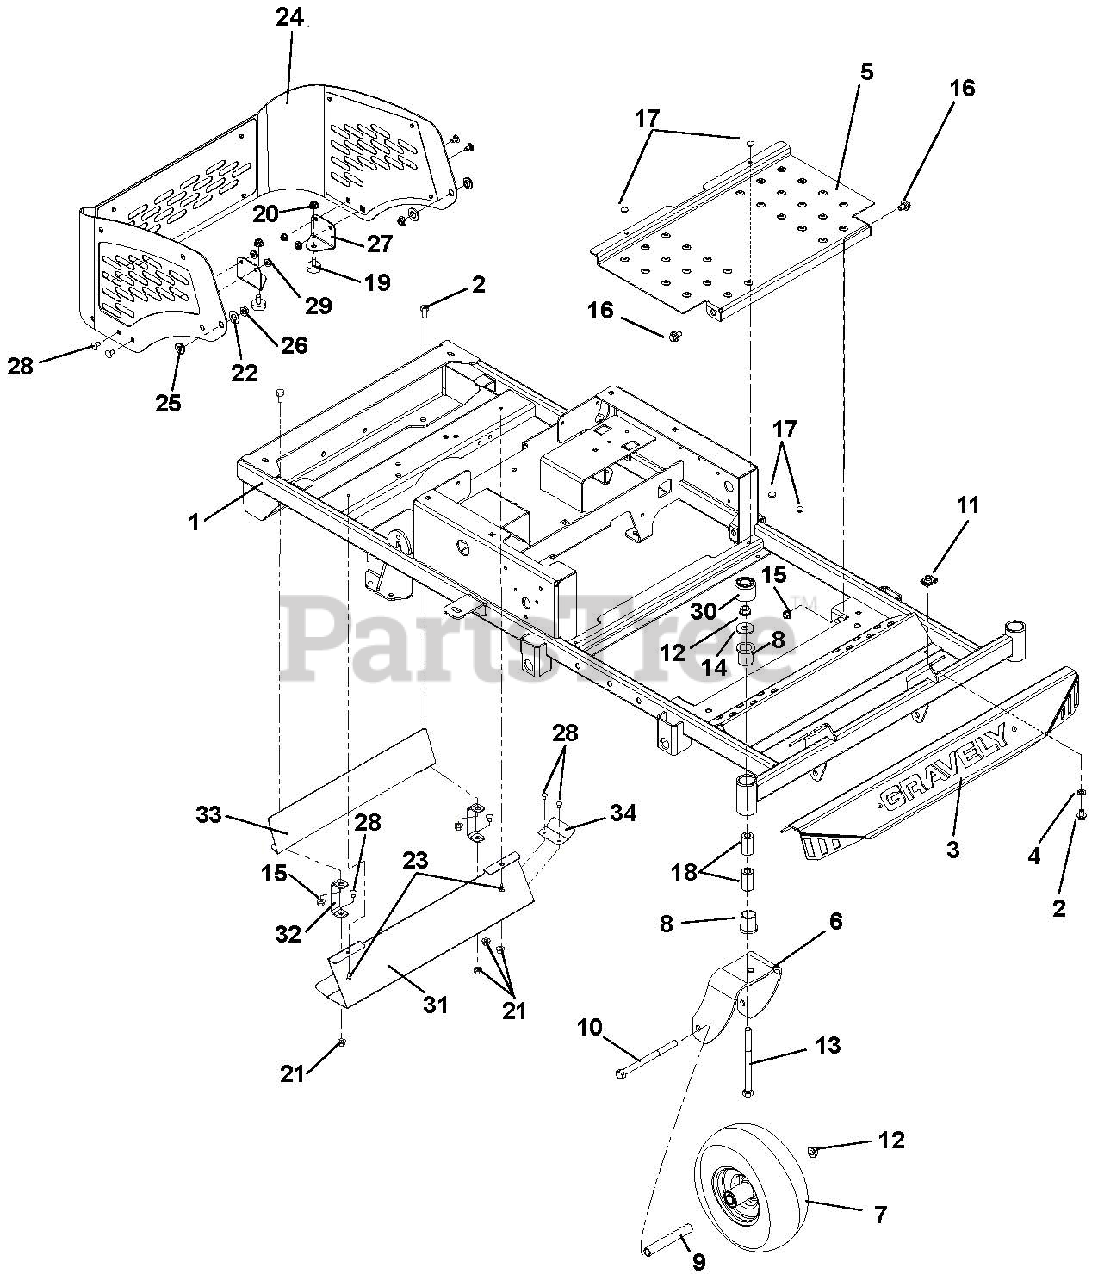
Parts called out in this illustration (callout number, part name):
1	Weldment, Frame XL
2	Bolt, Hex .38-16 x 1.00 Grade 5
3	Assembly, Foot-Rest XL
4	Washer, Locking .38 x .094 Regular
5	Deck Access Panel
6	Fork, Caster
7	Wheel/Tire Assembly, 11.0 x 4.0 x 5.0
8	Bushing, Flange 1.00 x 1.25 x 1.50 x 1.50
9	Spacer, Rolled Wheel
10	Bolt, Hex .50-13 x 6.50 Grade 5
11	Nut, Retainer .375-16 x .37
12	Nut, Locking Top Flange .50-13
13	Bolt, Hex .50-13 x 5.00 Grade 5
14	Washer, Flat Steel .511 x 1.441 x .125
15	Nut, Locking Top Flange .38-16
16	Bolt, Shoulder .375-16 x .135
17	Bumper Grommet .125 x .250 Diameter
18	Spacer, Caster Fork
19	Bumper, Rubber
20	Nut, Serrated Flange .31-18
21	Nut, Locking Top Flange .25-20
22	Washer, Flat Nylon .52 x 1.00 x .08
23	Screw, Tapping .25-20 x .50 Hex Washer Head Thread Rolling YWZ
24	Assembly, Engine Wrap XL
25	Bushing, Flange .325 x .499 x .3 x .875
26	Nut, Locking Center Flange .31-18
27	Brkt, XL Engine Wrap Foot
28	Bolt, Round Head Square Neck .25-20 x .50
29	Nut, Locking Center Flange .25-20
30	Cap, Dust
31	Guard, Muffler Heat
32	Strap, Muffler Guard
33	Shield, Hot Surface
34	Deflector, Heat Shield
